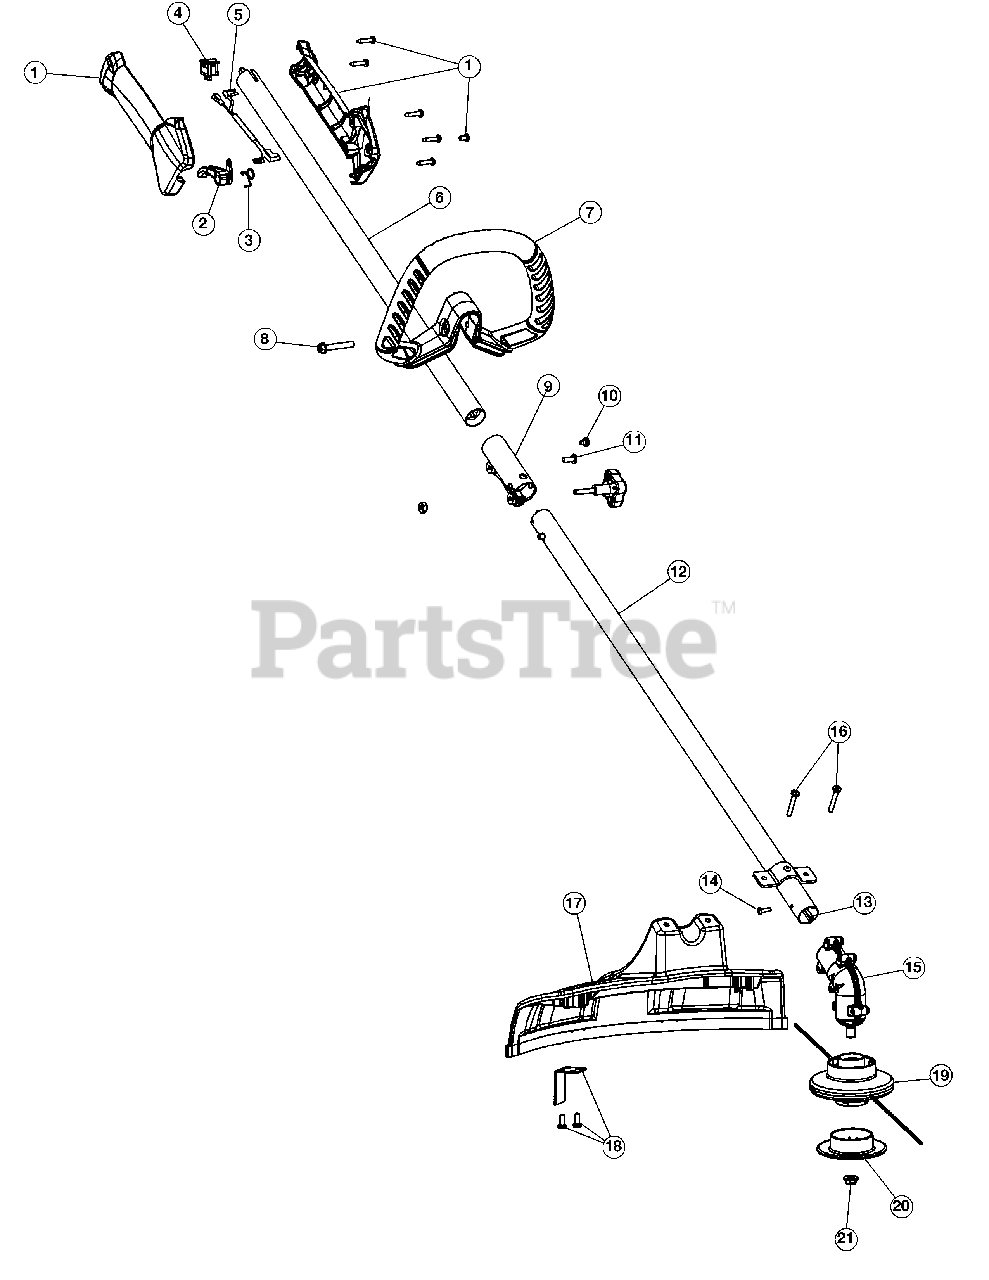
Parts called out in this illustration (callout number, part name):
1	Throttle Housing Assembly (Incl. 2 - 4)
2	Throttle Trigger
3	Throttle Trigger Spring
5	Throttle Cable Assembly
6	Upper Drive Shaft Housing Assembly
7	D-Handle Assembly (Incl. 8)
9	Split Boom Coupler (Incl. 10 and 11)
12	Lower Drive Shaft Housing Assembly
13	Lower Flexible Drive Shaft
14	Anti-Rotation Screw
15	Gear Box Assembly (Incl. 14)
16	Shield Mounting Screw
17	Shield Assembly (Incl. 18)
18	Blade Assembly
19	Cutting Head Assembly (Incl. 20 and 21)
20	Glide Cap
21	Lock Nut
